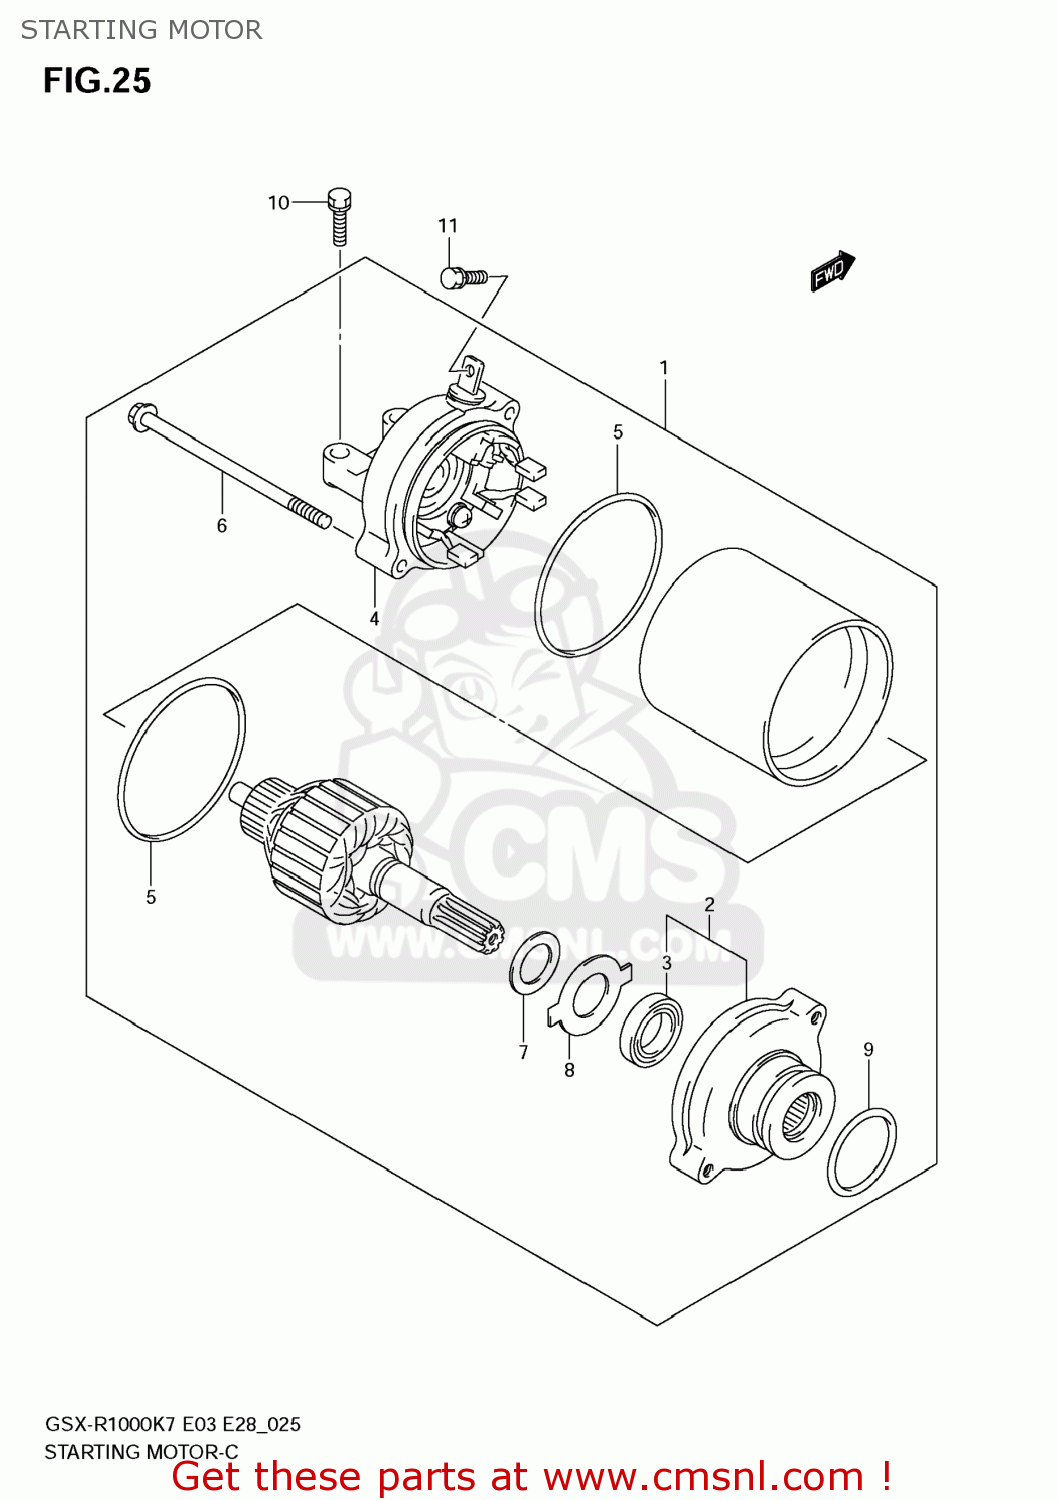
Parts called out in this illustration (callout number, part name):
1	MOTOR ASSY,STARTING
2	HOUSING ASSY
3	SEAL,OIL
4	FRAME ASSY
5	O RING
6	BOLT
7	PLATE,LOCK
8	SHIM
9	O RING(COLLAR:BROWN)
10	BOLT(6X20)
11	SCREW(5X8)
